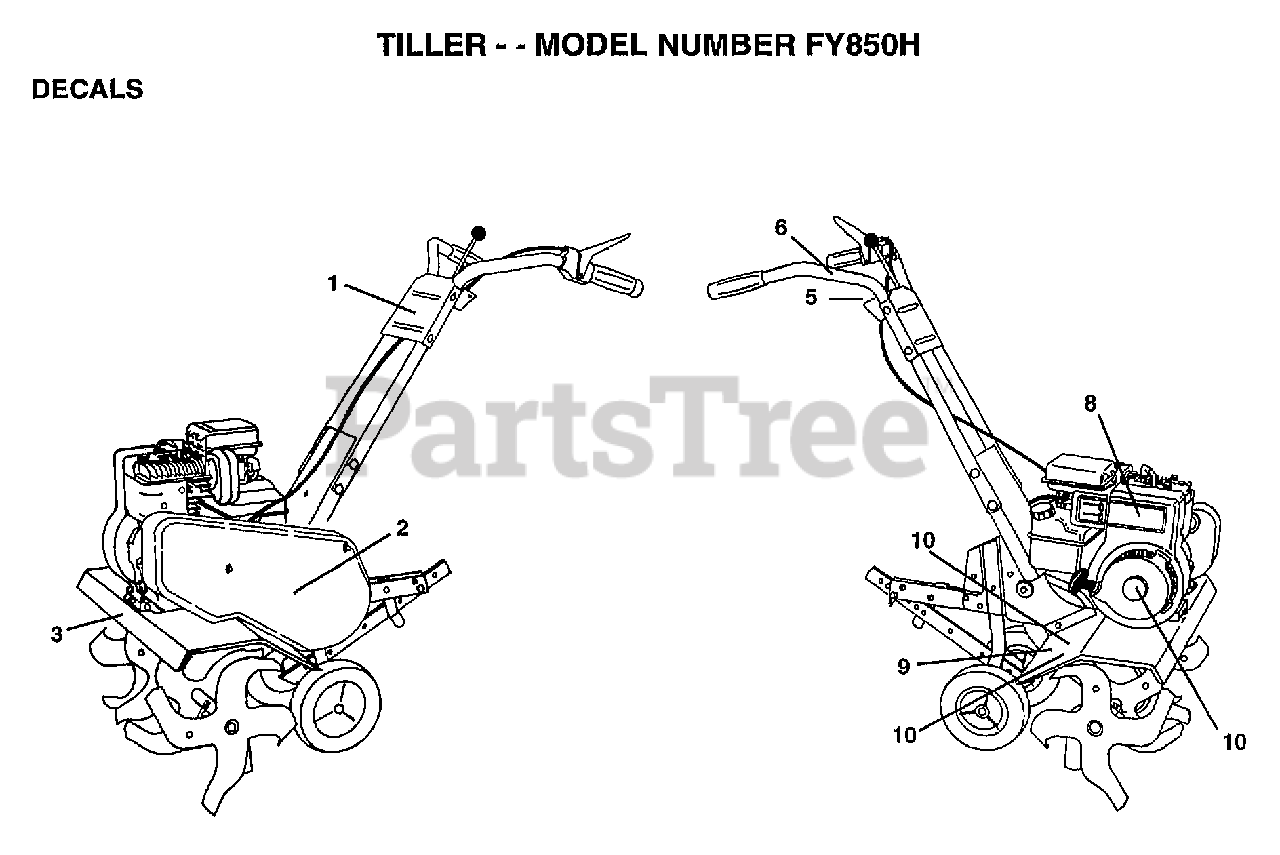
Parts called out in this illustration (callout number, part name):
1	DECAL HANDLE BRKT
2	DECAL.BELT.GUAR
3	DECAL TINE SHIELD
5	DECAL REVERSE
6	DECAL TI
11	DECAL.CAUTION
